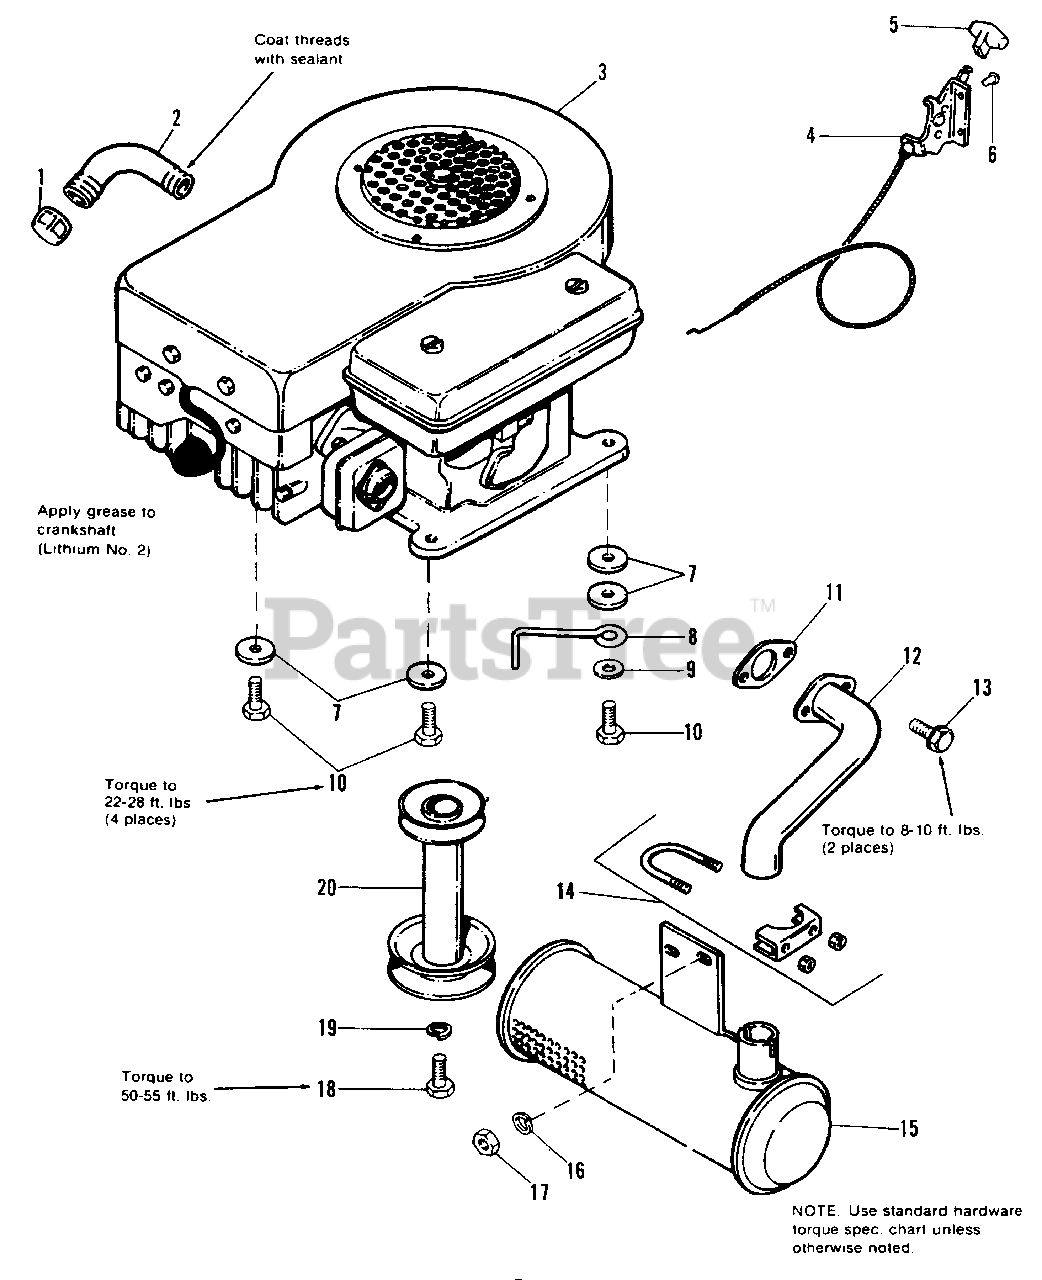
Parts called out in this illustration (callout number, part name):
1	CAP, Pipe, Hex
2	PIPE, Oil Drain
3	ENGINE ASSY., 8 H.P. Briggs & Stratton (6108 Only)
3	ENGINE ASSY., 11 H.P. Briggs & Stratton (6111 Only)
4	CONTROL ASSY.
5	KNOB
6	RIVET, Pop, 1/4 x 7/16
7	WASHER, Plain, 3/8
9	WASHER, Plain, 3/8
10	SCREW, Taptite 3/8-16 x 1-3/4
11	GASKET, Muffler (6111 Only)
12	PIPE, Exhaust (6111 Only)
13	SCREW, Whizlock, 5/16-18 x 3/4 (6111 Only)
14	CLAMP, Exhaust (6111 Only)
15	MUFFLER (6111 Only)
16	LOCKWASHER, 5/16 (6111 Only)
17	NUT, Hex, Full, 5/16-18 (6111 Only)
18	CAPSCREW, Hex 7/16-20 x 1-1/4
19	LOCKWASHER, 7/16
20	PULLEY ASSY., Engine
